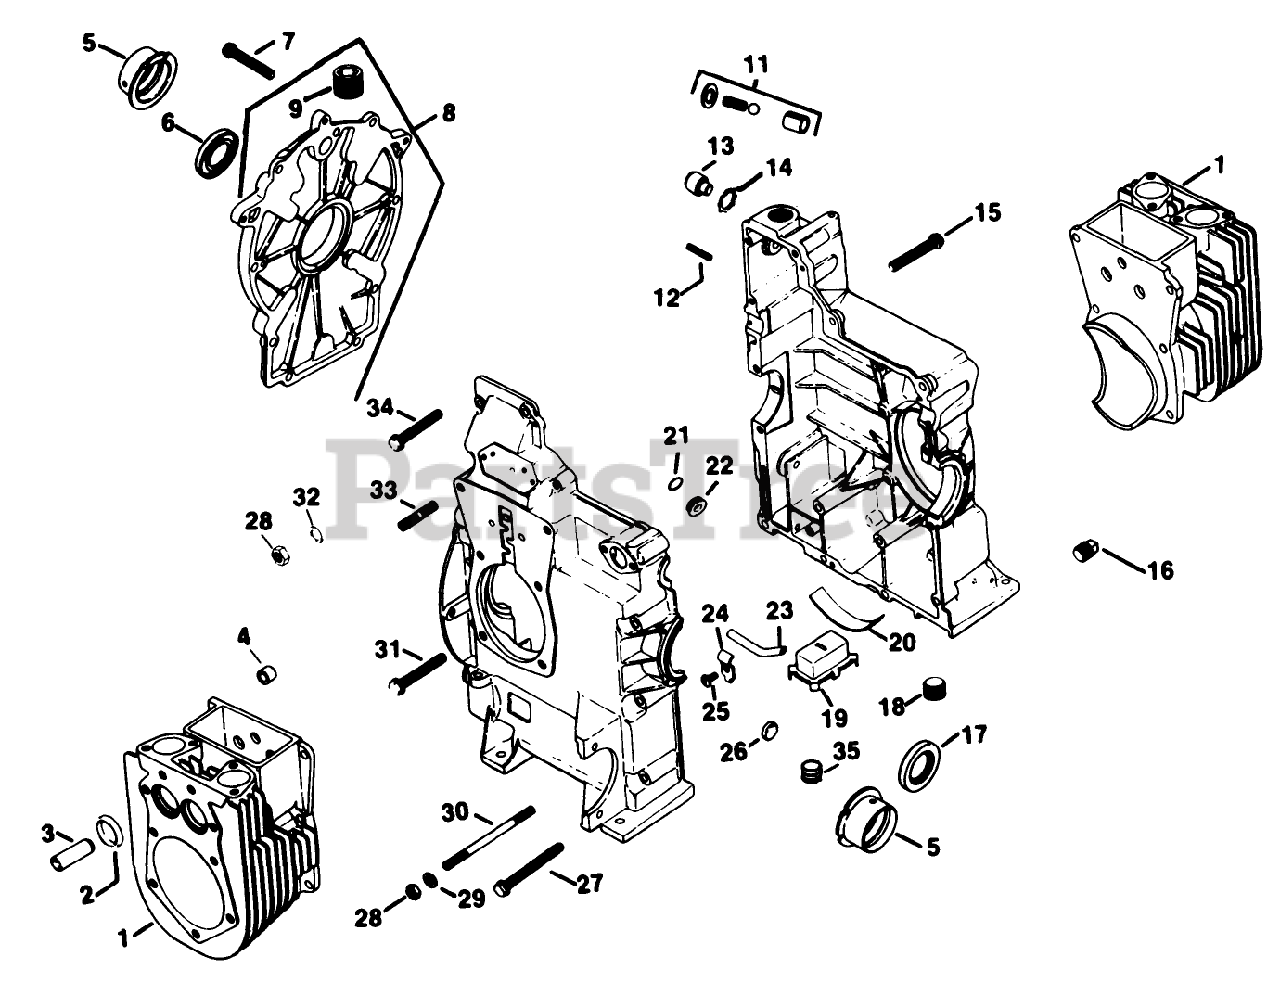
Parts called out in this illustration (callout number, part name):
1	Kit-Cylinder Barrel
2	Insert
3	Guide-Valve
4	Bushing-Locating
5	Bearing-Sleeve
6	Seal-RearOil
7	Screw-Wash Head
8	Kit-Rear Closure Plate
9	Plug
11	Kit-Oil Relief
12	Pin-Roll
13	Shaft-Governor
14	Ring-Retaining
15	Screw-Hex Flange
16	Plug
17	Seal-Rear Oil
18	Plug-Hex
19	Housing-Oil
20	Clip-Spring
21	O-Ring
22	Plug
23	Tube-Oil Pickup
25	Screw
26	Plug-Cup
27	Screw-Hex Flange
28	Nut
29	Washer-Flat
30	Stud
31	Screw-Hex Flange
32	Washer-Flat
34	Screw-Hex Flange
35	Plug-Pip Hex Ctsk
